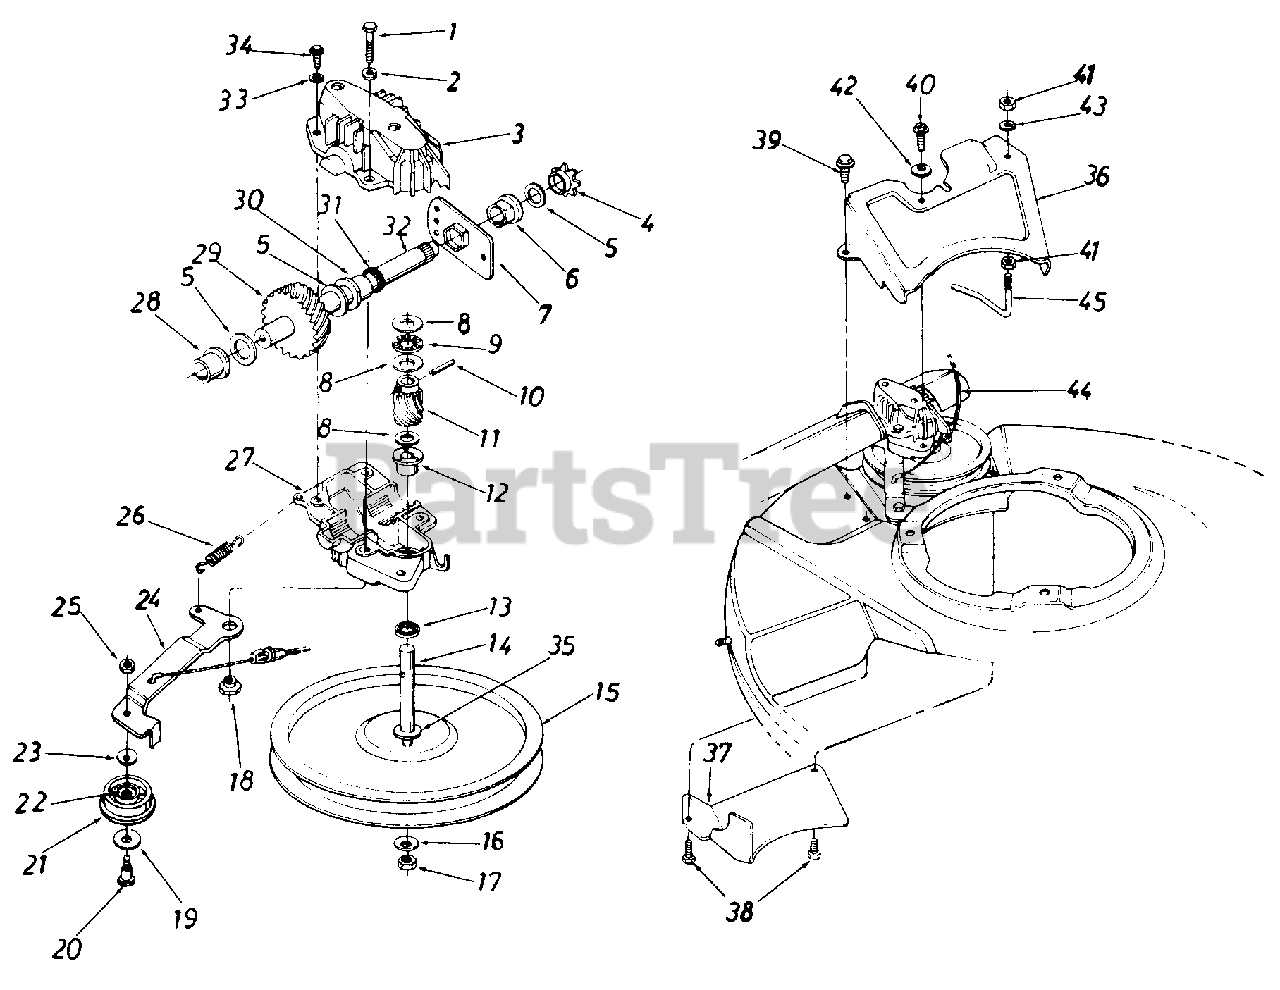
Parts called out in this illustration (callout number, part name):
1	Hex Bolt 1/4-20 x 1.25" Lg.
2	L-Wash. 1/4" I.D.
3	Upper Hsg. Half
4	#48 Sprocket 7 Tooth x 1/2 Pitch
5	Fl-Wash. 5/8" I.D. x .030
6	Hex Flange Brg. .631" I.D.
7	Hex Bearing Cup
8	Thrust Wash. .382" I.D. x .70" O.D.
9	Thrust Bearing .375" I.D. x .812" O.D.
10	Spring Pin Spir. 1/8" x .62" Heavy
11	11 Tooth Helical Gear
12	Flange Bearing
13	Oil Seal
14	Pulley-Transmission Shaft
15	Fl-Pulley 5.06" O.D.t
16	Bell-Wash. .265" I.D. x 75"
17	Hex L-Nut 1/4-28 Thd.
18	Shld. Spacer .375" Dia. x .170
19	Fl-Wash. .390" I.D. x 1.0"
20	Shld. Bolt .375" Dia. x .40"
21	Fl-Idler Plastic 1.50" Dia.
22	Needle Brg. .375" x .31
23	Bell-Wash. .265" I.D. x .75"
24	Idler Brk t. Ass y
25	Hex Patch L-Nut 1/4-28 Thd.
26	Extension Spring 1.12" Lg.
27	Lower Hsg. Half
28	Flange Bearing .566 Dia.
29	33 Tooth Helical Gear
30	Flange Bearing .629 Dia.
31	Oil Seal .625 Dia.
32	Gear Sprocket Shaft
33	L-Wash. #10 I.D.
34	Hex B-Tap Scr. #10x .62"
35	Hex Washer .26" x .88"
36	Transmission Belt Guard
37	Belt Cover
38	Hex B-Tap Scr. 1/4 x .38" Lg.
39	Hex AB-Tap Scr. 1/4 x .50" Lg.
40	Hex B-Tap Scr. 1/4 x .62" Lg.
41	Hex Nut 1/4-20 Thd.*
42	Bell-Wash. .265" I.D. x 75"
43	L-Wash. 1/4" I.D.
44	S.P. Cable-50" Lg.
45	S.P. Belt Guard
